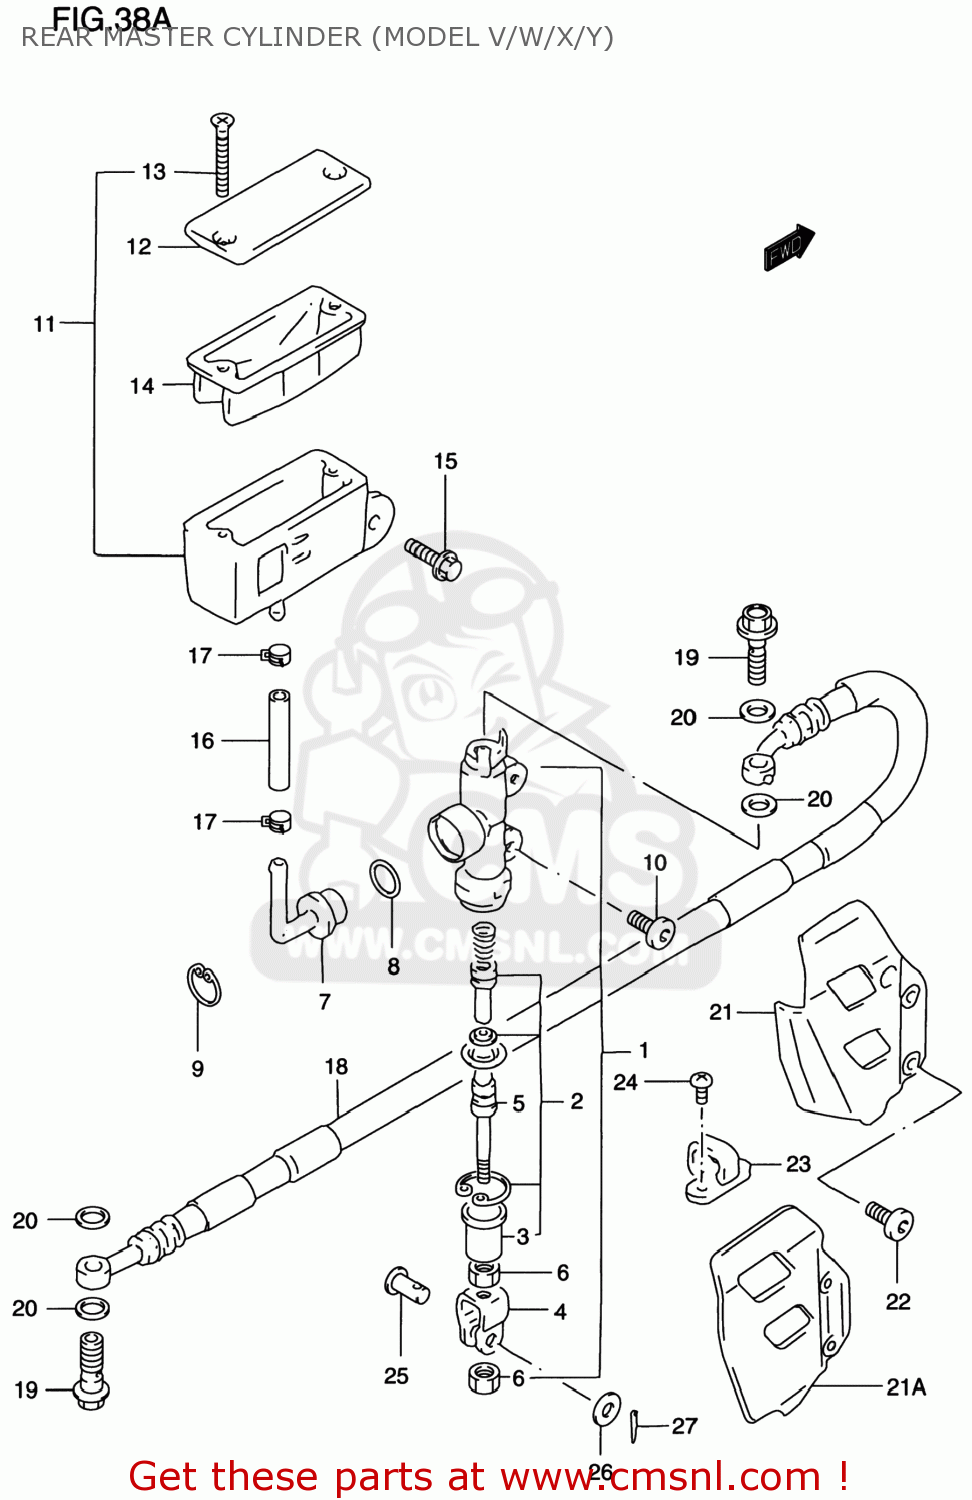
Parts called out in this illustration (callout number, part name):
1	CYLINDER ASSY,RR MASTER
2	PISTON/CUP SET
3	BOOT
4	YOKE
5	ROD,PUSH
6	NUT
7	CONNECTOR
8	O RING
9	CIRCLIP
10	SCREW(6X16)
11	TANK ASSY,RESERVOIR
12	CAP
13	SCREW
14	DIAPHRAGM
15	BOLT
16	HOSE,FR RESERVOIR TANK
17	CLAMP,RESERVOIR HOSE
18	HOSE COMP,REAR BRAKE
19	BOLT UNION
20	WASHER(10X15X1.5)
21	GUARD,RR MASTER CYLINDER
21A	GUARD,RR MASTER CYLINDER
22	SCREW(6X16)
23	GUIDE,RR BRAKE
24	SCREW
25	PIN(8X20)
26	WASHER(8.5X13X1.6)
27	PIN
